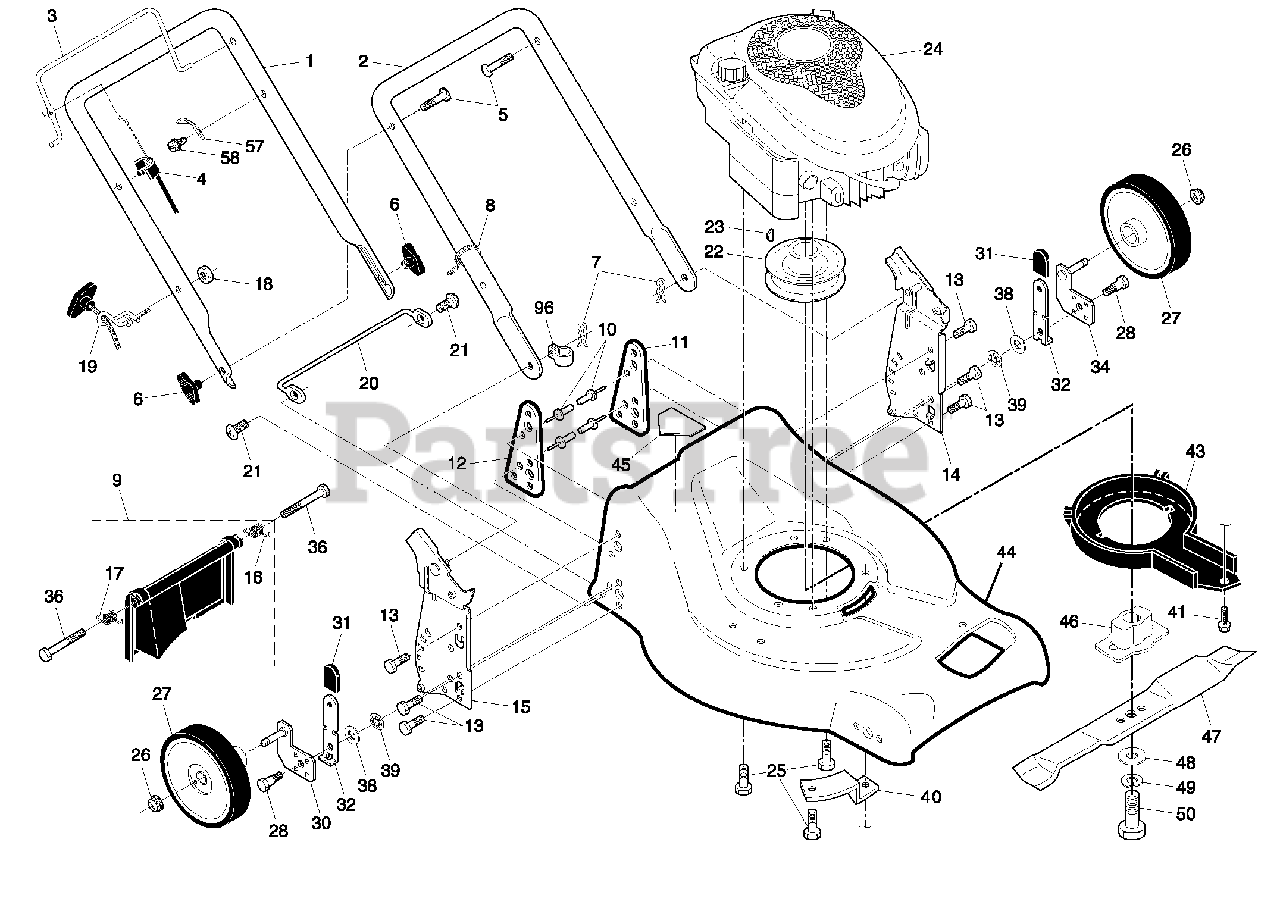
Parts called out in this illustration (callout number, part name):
1	Upper Handle
2	Lower Handle
4	Engine Zone Control Cable
6	Handle Knob
7	Hairpin Cotter
8	Wire Tie
9	Rear Door Kit
11	Support Bracket, LH
12	Support Bracket, RH
13	Screw 1/4-20 x 5/8
14	Handle Bracket Assembly, LH
15	Handle Bracket Assembly, RH
16	Spring, Rear Door, LH
17	Spring, Rear Door, RH
18	Keps Locknut 1/4-20
19	Rope Guide
20	Foot Guard, C.E.
21	Screw, Tapping 1/4-20 x 1/2
22	Engine Pulley
25	Hex Head Thread Rolling Screw 3/8-16 x 1-1/8
26	Hex Flange Nut
27	Wheel & Tire Assembly
28	Shoulder Bolt 5/16-18 x .33
30	Axle Arm Assembly, Rear, RH
31	Selector Knob
32	Selector Spring
34	Axle Arm Assembly, Rear, LH
36	Bolt, Hex Head
40	Mounting Bracket, Debris Shield
43	Debris Shield
44	Kit, Lawn Mower Housing
45	Danger Decal
46	Blade Adapter
47	Blade, 21"
48	Hardened Washer
49	Helical Washer 3/8-24 x 1-3/8 Grade 8
50	Hex Head Machine Screw 3/8-24 x 1-3/8 Grade 8
57	Bracket, Upstop
58	Screw, Threaded 10-24 x 1/2
96	Operator's Manual, European
96	Operator's Manual, Scandinavian
96	Repair Parts Manual, English
